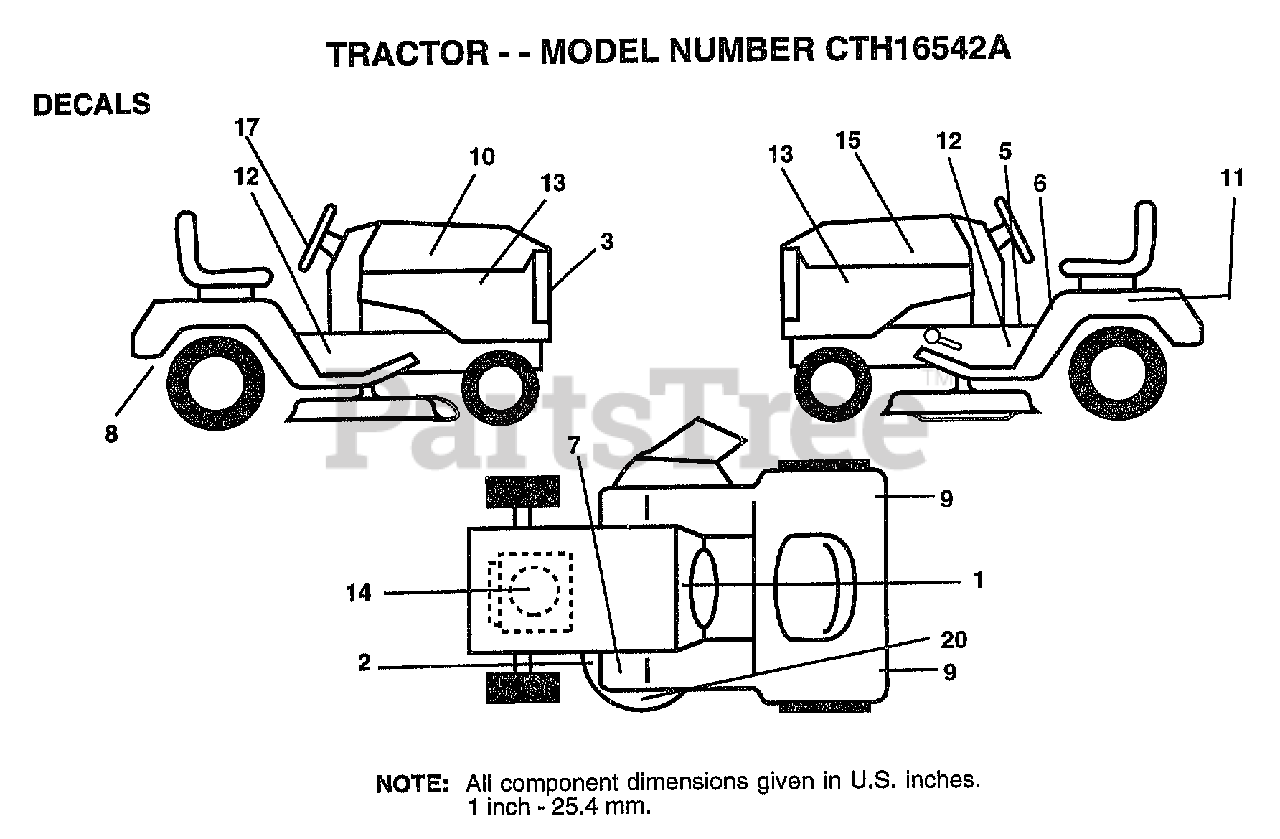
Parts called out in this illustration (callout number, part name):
1	"DECAL-INST,OPER"
2	"DECAL-SCHEM,BELT"
3	DECAL GRILLE
5	DECAL BRAK PARK
6	"DECAL DANGER,FEND"
8	DECAL DRAWBAR LH
9	REFLECTOR-TAIL YT
10	DECAL.HOOD.RH
11	DECAL.BATRY.3-3908
12	"DECAL CHASSIS 42"""
13	DECAL SIDE PANEL
14	DECAL ENGINE
15	DECAL.HOOD.LH
17	DECAL INST STG WH
20	"DECAL,ENVIRO DECK"
